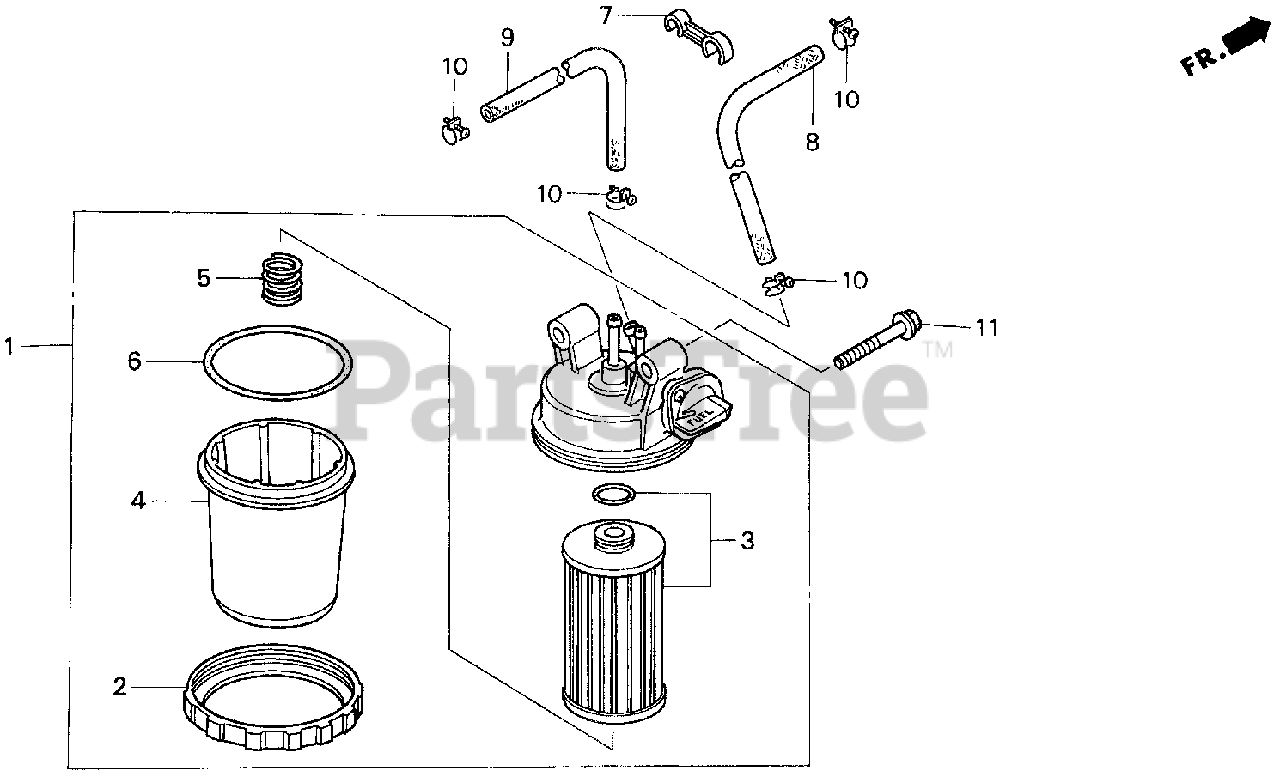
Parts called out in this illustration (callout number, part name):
1	FILTER ASSY., FUEL
4	CHAMBER, STRAINER
5	SPRING, COIL
7	CLIP, TUBE
8	BULK HOSE, FUEL (7.5X3000) (7.5X280)
9	BULK HOSE, FUEL (7.5X3000) (7.3X400)
10	CLIP, TUBE (D13)
11	BOLT, FLANGE (8X30)
12	CLIP, CABLE
